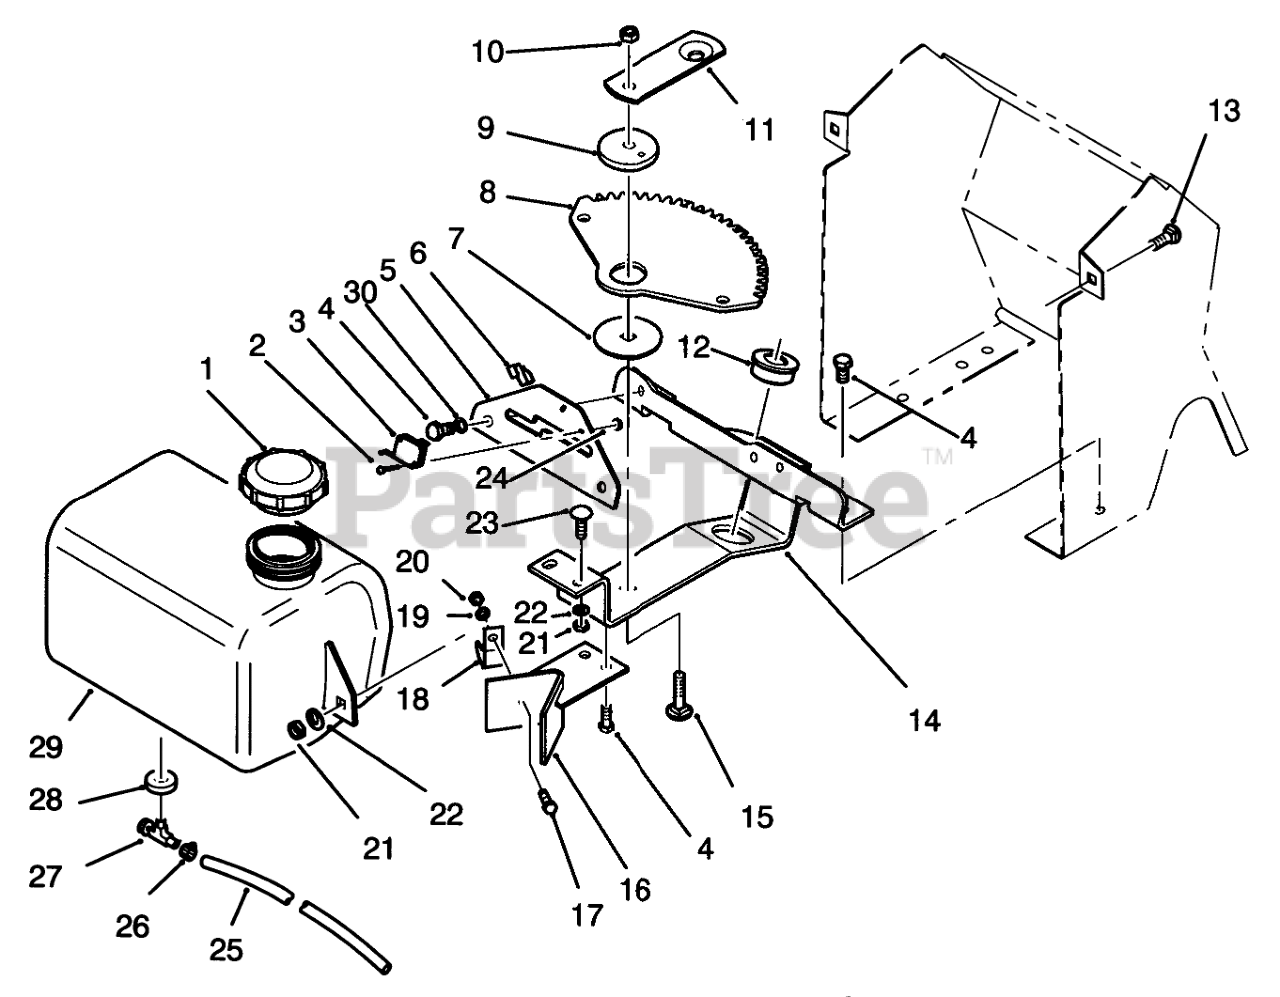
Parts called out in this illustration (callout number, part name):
1	CAP GAS
2	Screw
3	SWITCH - CLUTCH
4	Screw
5	PLATE-SHIFT R
6	CLIP-CABLE
7	WASHER-BEARING
8	GEAR-SECTOR
9	BUSHING
11	Plate
12	BEARING-WHEEL
13	SCREW-CARR
14	STEERING BRKT - W/A R
15	BOLT-CARR
16	Stop
17	Bolt
18	CLIP
20	NUT-LOCK, NI
21	NUT-LOCK, NI
22	WASHER-PLAIN
23	Bolt-Carriage
24	NUT HEX 4-40 ELAST
25	FUEL HOSE(1 FT.6554)
26	CLAMP-HOSE
27	VALVE-FUEL
28	BUSHING
29	Tank-Fuel (Incl. Ref. #27-29)
